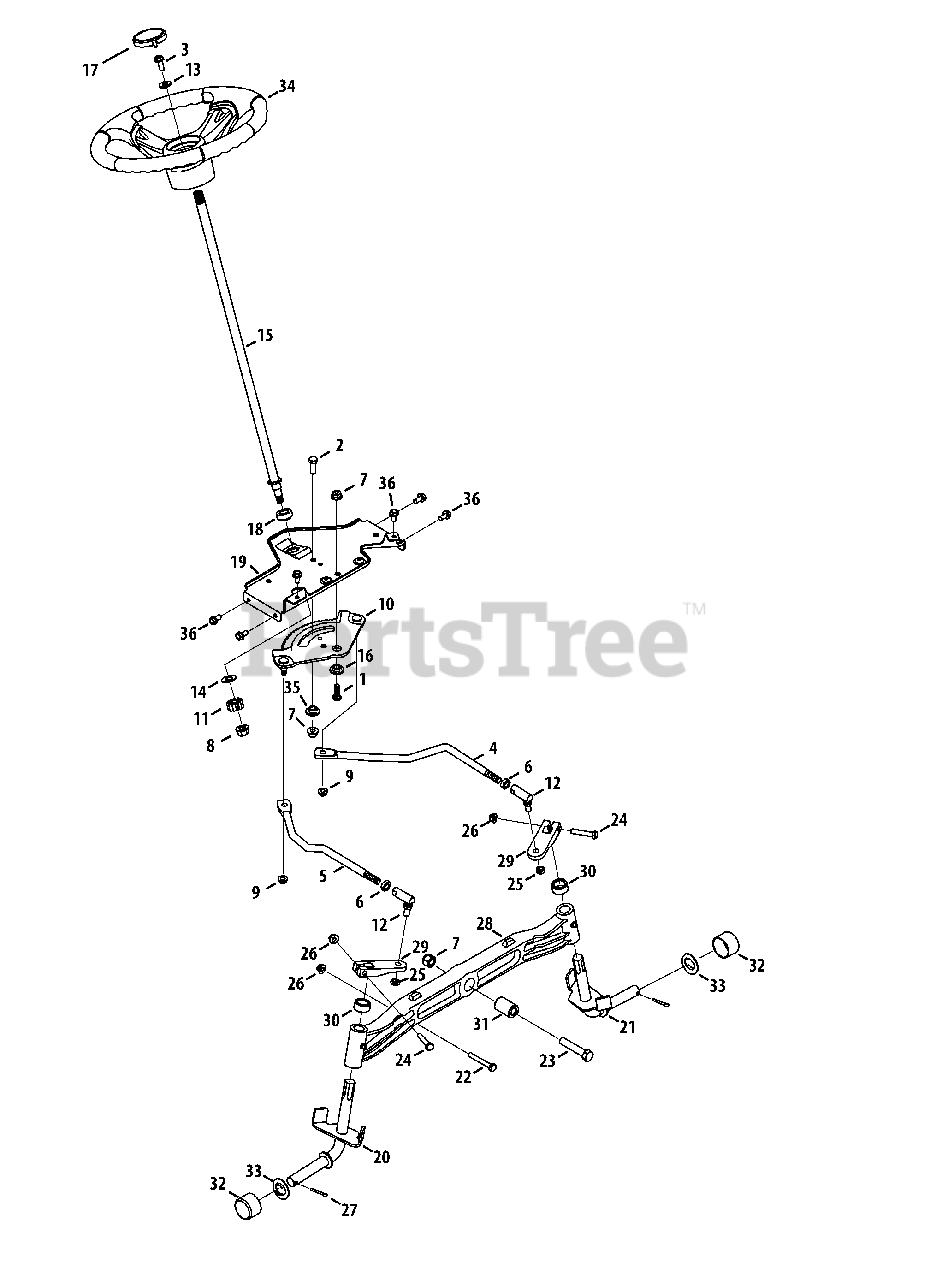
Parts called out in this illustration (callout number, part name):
1	Hex Screw, 3/8-16, 1.00, Gr5, Spec
2	Hex Screw, 3/8-16, 1.00, Gr5, Std
3	Hex Screw, 5/16-18, .875, Gr5, Lock
4	Link, Drag LH
5	Link, Drag RH
6	Nut, Jam, 7/16-20, Gr2
7	Nut, Flange Lock, 3/8-16, Grf,
8	Nut, Flange Lock, 7/16-20, Grb, Lock
9	Nut, Flange Lock, 5/16-18, Gr5, Sd Lk
10	Gear, Steering, 11/90 Ratio
11	Gear, Pinion, Steering
12	Ball Joint, 7/16-20, Lock
13	Washer, Flat, .406 x .875 x .105
14	Washer, Flat, .51 x 1.12 x .06
15	Shaft, Steering, .625 OD x 25, Cub
16	Spacer, Shoulder, .385x 1.25 x .3025
17	Cover, Steering Wheel, Cub Cadet
18	Bearing, Flange, Hex 5/8 Pm
19	Bracket, Support, Steering
20	Axle Ass’y, RH .750 Dia.
21	Axle Ass’y, LH .750 Dia.
22	Hex Screw, 5/16-18, 2.25, Gr5, Std
23	Hex Screw, 3/8-16, 2.50, Gr5, Std
24	Hex Screw, 5/16-18, 1.75, Gr5, Std
25	Nut, Hex Lock, 3/8-24, Grb
26	Nut, Flange Lock, 5/16-18, Grf
27	Pin, Cotter, 5/32, 1.25
28	Axle, Pivot Bar, Cast
29	Steering, Block
30	Spacer, .71 ID x .125 OD x .56
31	Spacer, .385 x 1.00 x 1.5075
32	Cap, Bumper
33	Washer, Flat, .350 x 1.559 x .062
34	Wheel, Steering, 3 Spoke, Softgrip
35	Spacer, .38 x 1.375
36	Screw, Self-tapping, 5/16-18, .750,
